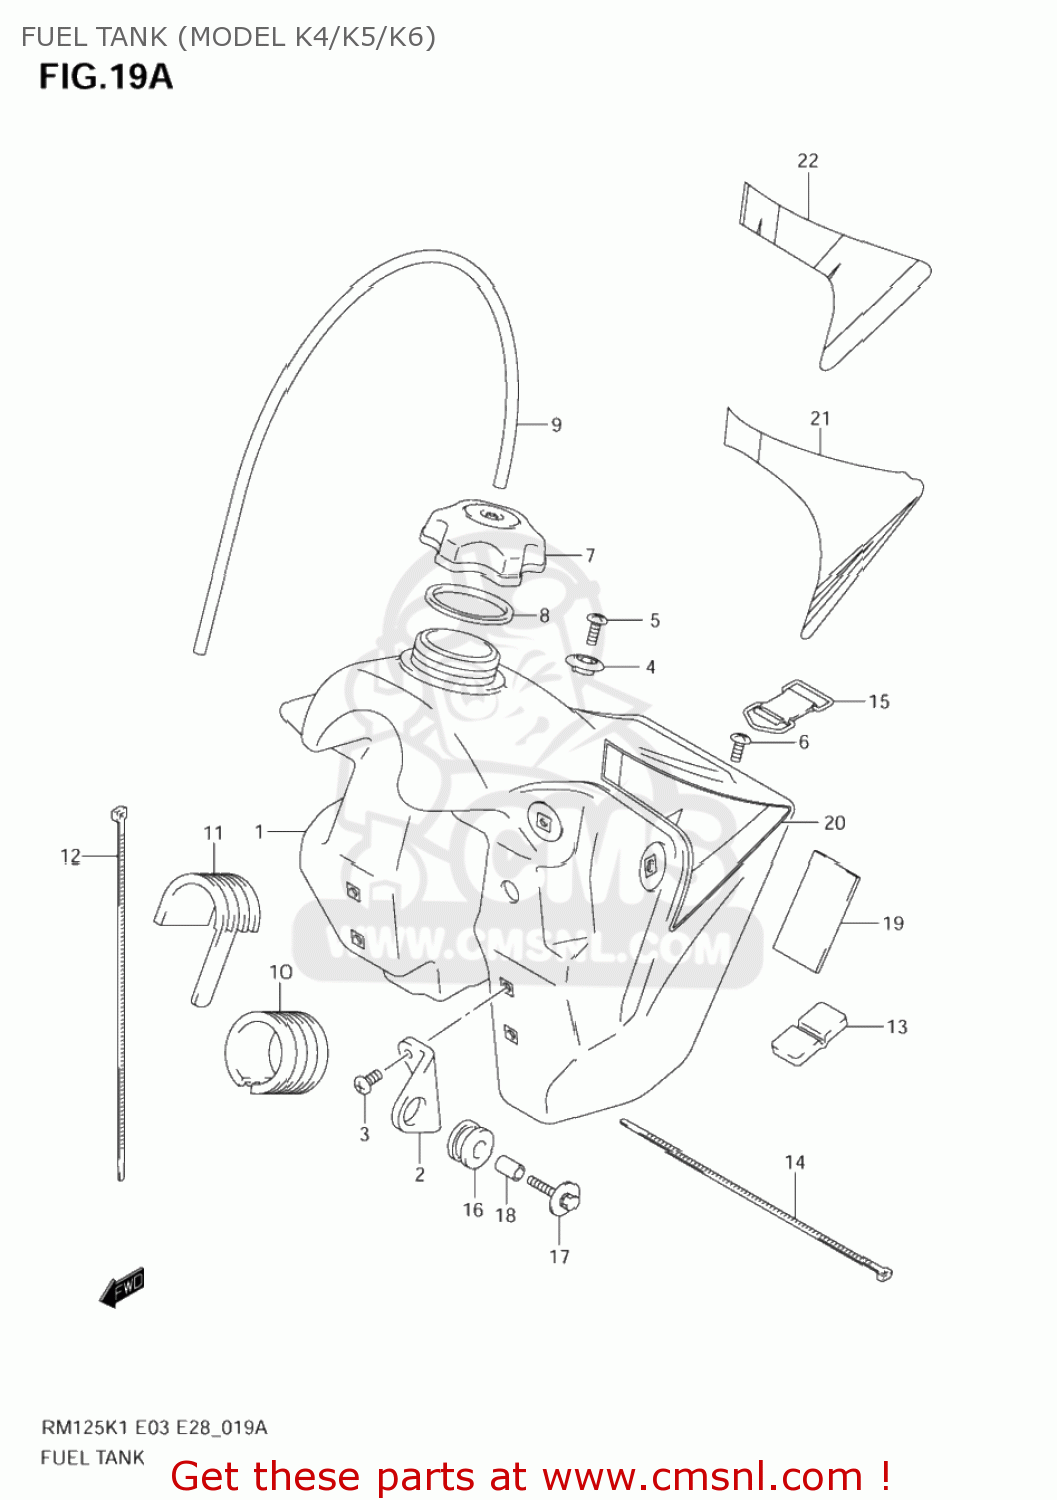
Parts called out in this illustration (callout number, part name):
1	TANK COMP,FUEL
2	BRACKET,FUEL TANK FR
3	SCREW 6X12
4	HOOK,SEAT FR
5	SCREW
6	SCREW(6X13.5)
7	CAP,FUEL TANK FILLER
8	GASKET,CAP (NAS)
9	HOSE(5X8.2X600)
10	CUSHION,FUEL TANK NO.1
11	CUSHION,FUEL TANK
12	CLAMP(L:300)
13	CUSHION,FUEL TANK RR
14	CLAMP(L:250)
15	BAND,FUEL TANK RR
16	CUSHION,MUFFLER
17	BOLT(6X35)
18	SPACER(6.5X9X13.5)
19	PROTECTOR(40X85X5)
20	TAPE SET,FUEL TANK
21	TAPE SET,FUEL TANK
22	TAPE SET,FUEL TANK
